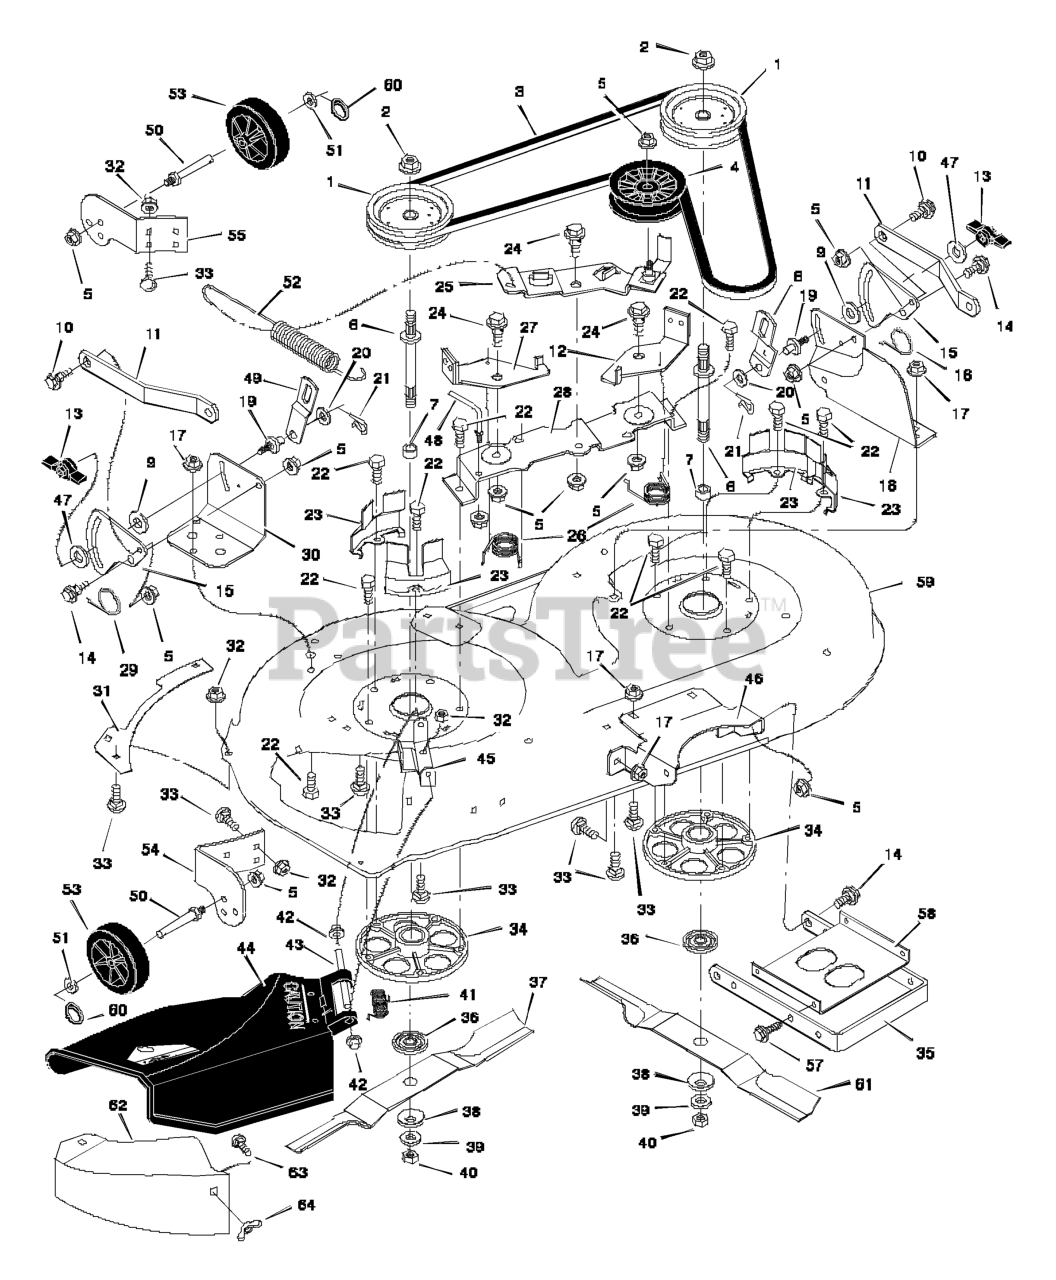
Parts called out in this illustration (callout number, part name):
1	Pulley, Jackshaft
2	Nut, Hex
3	Belt, Mower Drive
4	Pulley, Idler
5	Nut, Flange
6	Jackshaft
8	Link, Left Lift
9	Pad, Friction
10	Bolt, Shoulder
11	Bracket, Suspension
12	Pad Assembly, Left Brake
13	Knob
14	Bolt, Shoulder
15	Plate, Suspension
17	Nut, Flange
18	Bracket, Suspension
19	Pin, Hanger
21	Pin, Hair
22	Bolt
23	Cover, Pulley
24	Bolt, Shoulder
25	Arm, Idler
27	Pad Assembly, Right Brake
28	Bracket, Brake
30	Bracket, Suspension
32	Nut, Flange
33	Bolt, Carriage
34	Mandrell Housing
35	Bracket, Suspension
36	Adapter, Blade
37	Blade, Right (Mulching)
42	Cap, Push On
43	ROD, Deflector
44	Deflector
45	Bracket, Deflector Hinge
46	Bracket, Front Hanger
48	Guide, Belt
49	Link, Right Lift
50	BOLT, Gauge Wheel
52	Spring, Extension
53	Wheel, Gauge
54	Bracket, Right Wheel
55	Bracket, Left Wheel
56	Brace, Hanger
58	Stiffener
59	Housing, Blade
60	Ring, Locking
61	Blade, Left (Mulching)
62	Cover, Mulcher
63	Bolt, Carriage
64	Wingnut
